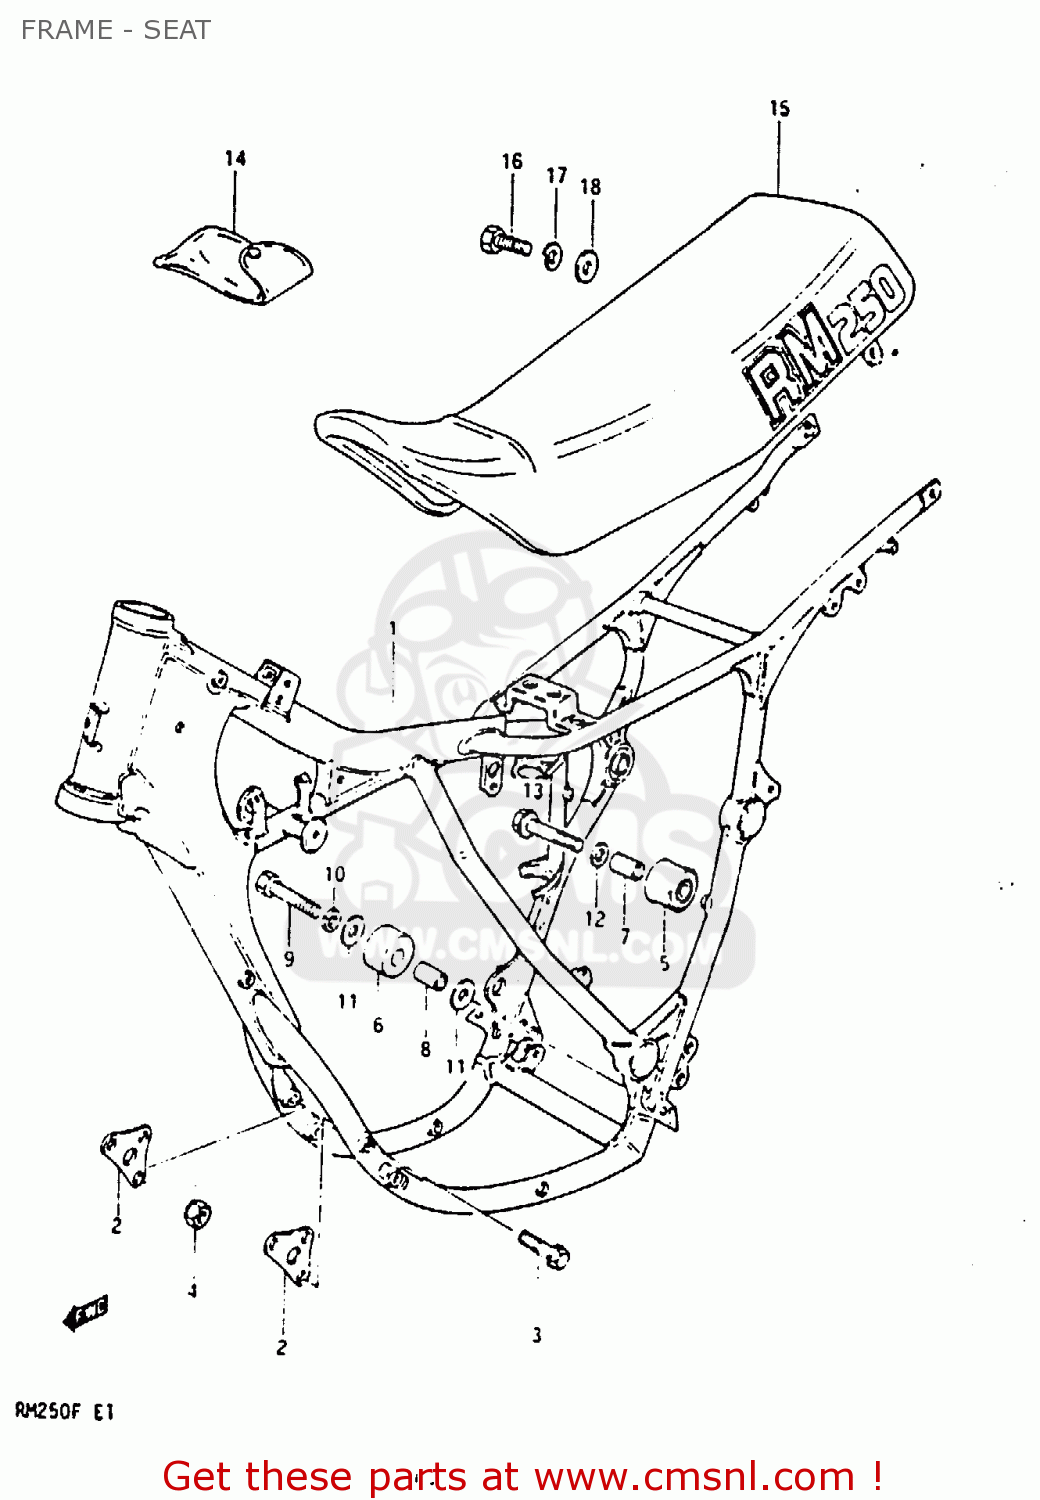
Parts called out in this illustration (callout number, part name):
1	FRAME
2	PLATE,ENGINE MOUNTING
3	BOLT 8X55
4	NUT
5	ROLLER,CHAIN
6	ROLLER,CHAIN LENGTH CONTROL
7	SPACER,CHAIN LENGTH ROLLER
8	SPACER(8.6X12X25.5)
9	BOLT 8X45
10	WASHER,LOCK,8.
11	WASHER (8.5X25X1.2)
12	WASHER
13	BOLT(8X45)
14	TOOL SET
15	SEAT ASSEMBLY
16	BOLT
17	LOCK WASHER
18	WASHER
